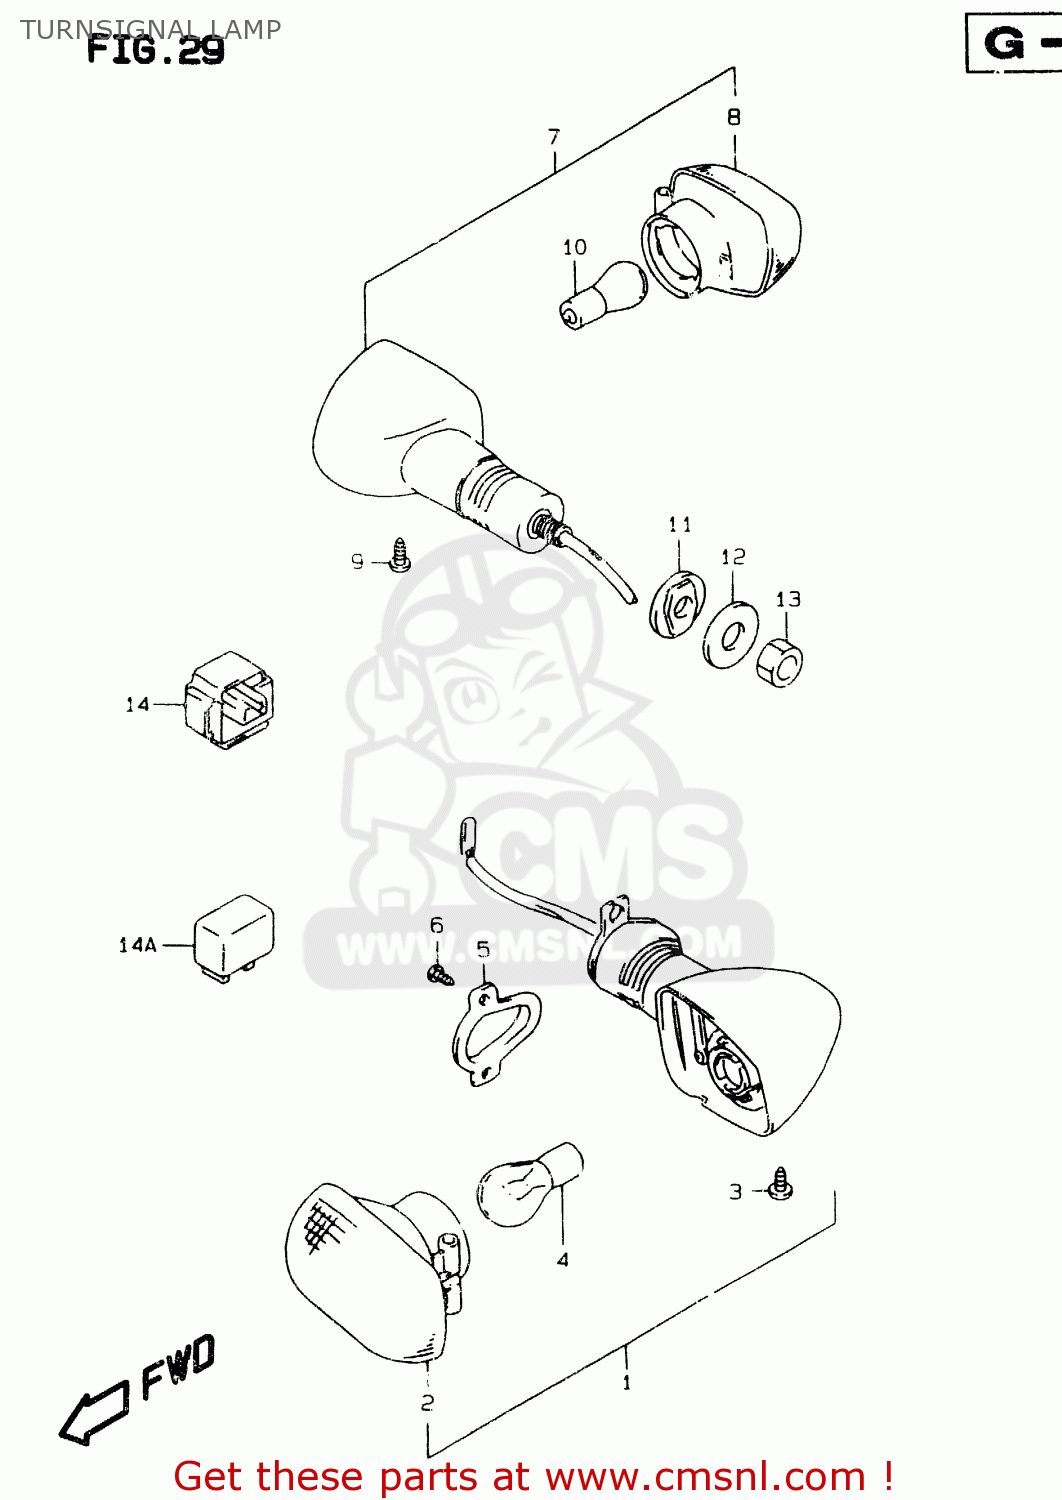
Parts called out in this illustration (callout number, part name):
1	LAMP ASSEMBLY,FRONT TURN SIGNAL
2	LAMP UNIT
3	SCREW
4	BULB(12V21W)
5	PLATE,FR TURNSIGNAL LAMP
6	SCREW
7	LAMP ASSY,RR TURNSIGNAL,R
8	LAMP UNIT
9	SCREW
10	BULB(12V21W)
11	SPACER,RR TURNSIGNAL
12	WASHER(10.5X30X2.3)
13	NUT
14	RELAY ASSY
14A	RELAY ASSY,TURNSIGNAL LAMP
